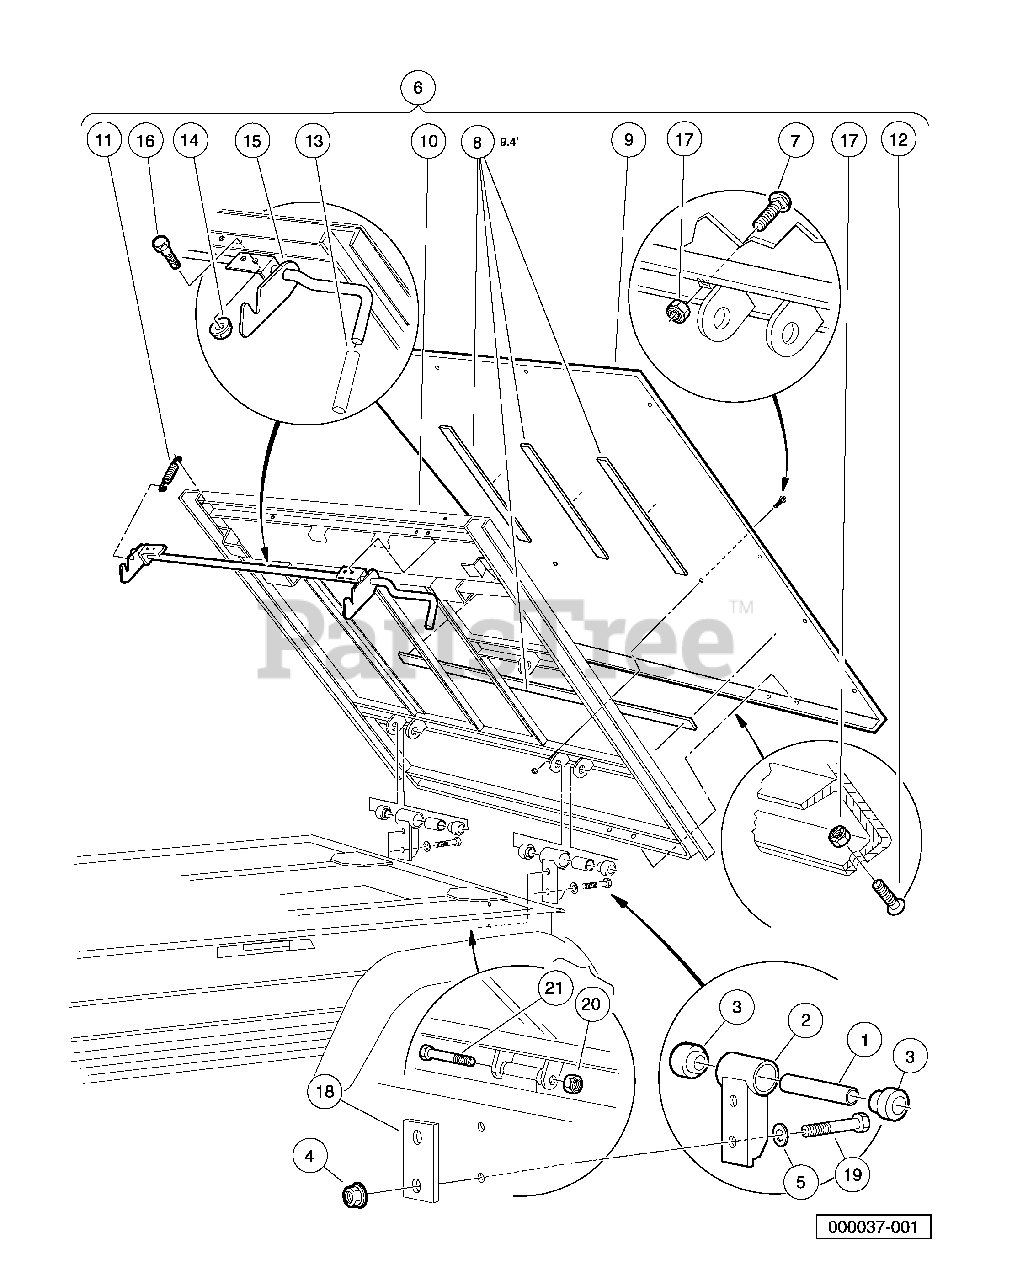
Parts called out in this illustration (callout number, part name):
1	Bushing, Steel
3	Bushing, Urethane
4	Locknut, 3/8-16 Flanged Dimple
5	Washer, 3/8 Type B Hard Flat
6	Tilt Bed Assembly
7	Bolt, Carriage, 5/16-18 X 1.00
8	Tape, Vinyl Foam 1/8" x 3/4" *
9	Plate, Floor Bed
10	Frame Assembly
11	Extension, Spring Latch
12	Screw, 5/16-18 X 0.88 Torx Truss-Head
13	Grip, Tilt Latch Hand
14	Locknut, 1/4-20 Hex Whiz
15	Ltch Weld Asm Tlt Bd
16	Screw, 1/4-20 X 0.625 Hex-Head Cap
17	Locknut, 5/16-18 Nylon Insert
18	Plate, Back
19	Bolt, 3/8-16 X 3.00 Hex Head
20	Locknut, 3/8-16 Hex
21	Screw, 3/8-16 X 3.375 Hex Cap
